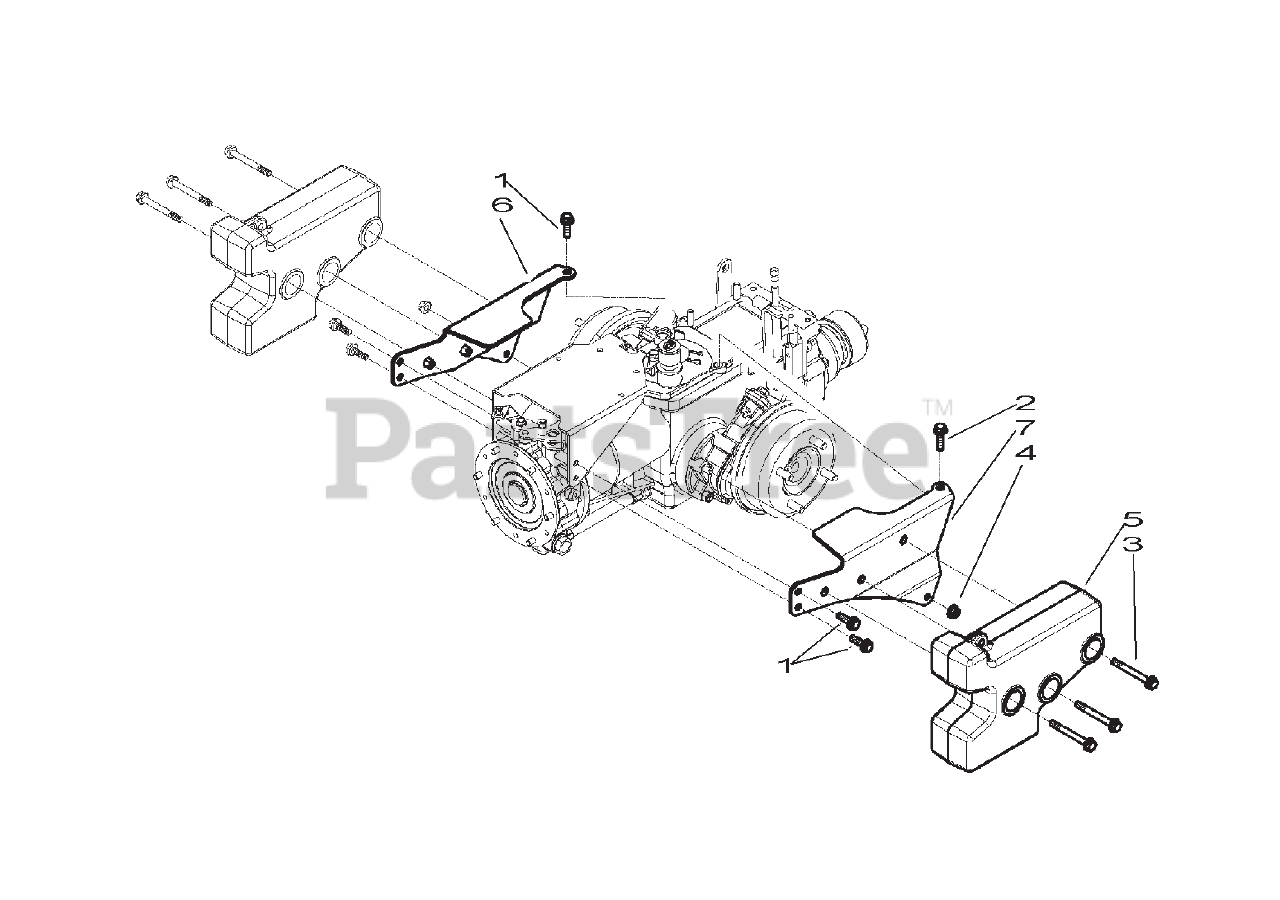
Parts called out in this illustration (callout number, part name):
1	SCREW TE C/F M8X25 DIN 6921 8G
2	SCREW TE C/F M8X30 DIN 6921 8G
3	SCREW
4	SELFLOCK NUT M8 6S DIN 6927
5	WEIGHT
6	BRACKET
7	BRACKET
